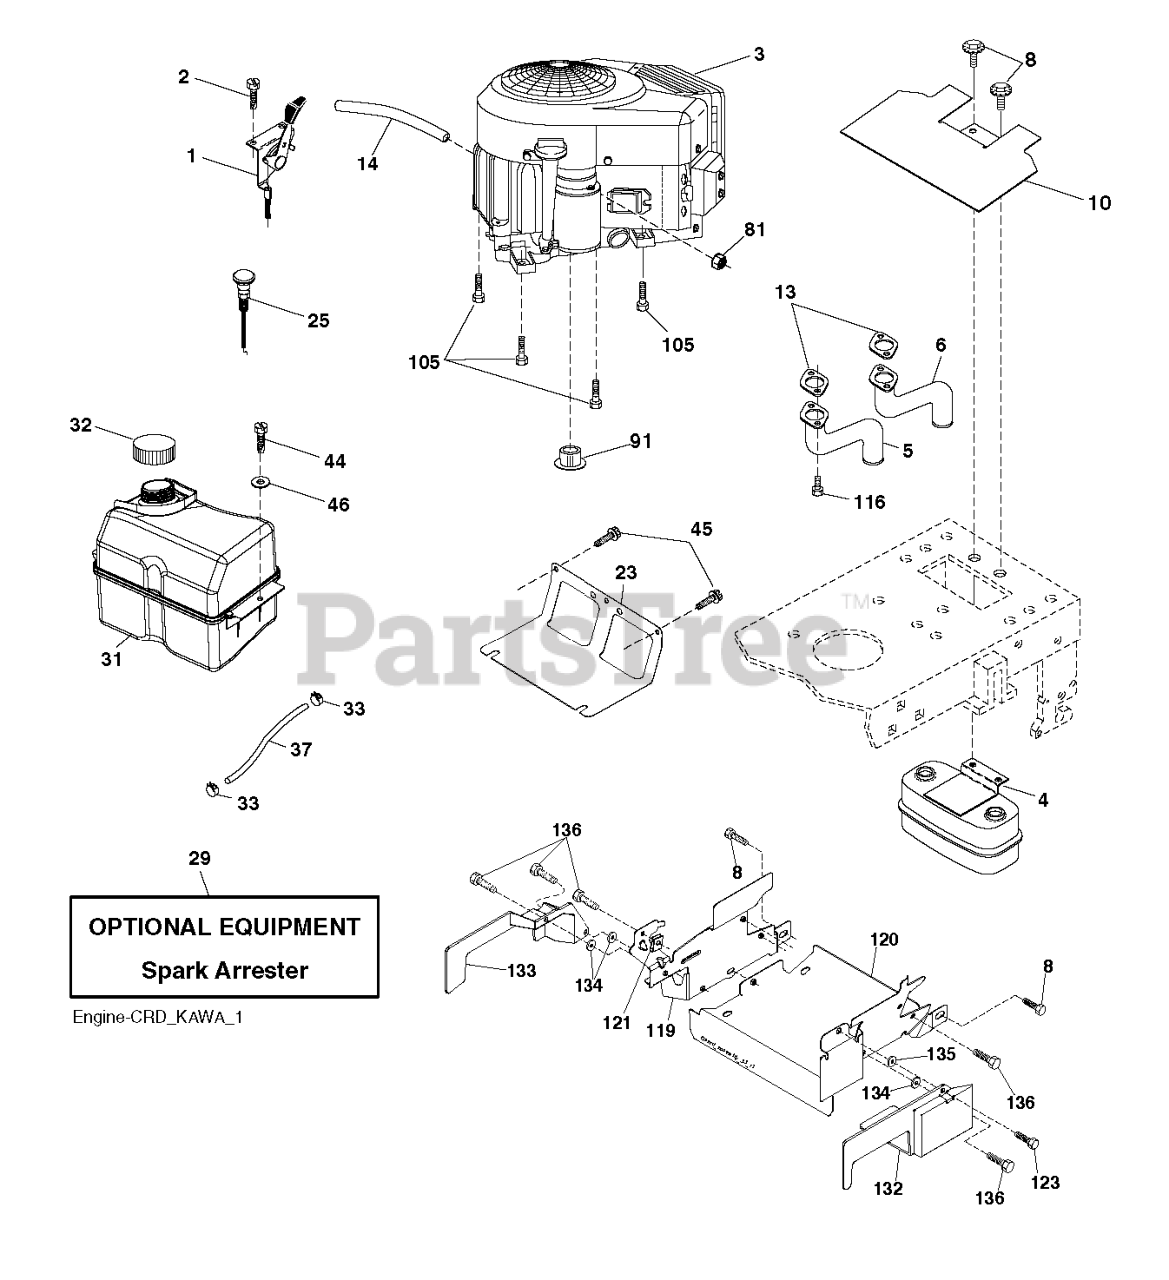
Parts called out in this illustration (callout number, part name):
1	THROTTLE CONTROL
2	SCREW
4	MUFFLER.TWIN.CYL.LOW.TONE
5	TUBE.EXHAUST.LH.FR961/FR730
6	TUBE.EXHAUST.RH.FR961/FR730
8	BOLT.5/16-18UNCX3/4 W/SEMS.BLK
10	SHIELD.HEAT.MUFFLER
14	TUBE, DRAIN OIL ASM.
23	SHIELD.BROWNING.DBR.GUARD
25	CONTROL, CHOKE, 37", PUSH
29	KIT.SPARK ARRESTOR 794945 B&S
31	TANK.ASM.FRNT.DAPCO.E10
32	CAP ASM.FUEL.2.25"FR.
33	HOSE CLAMP
37	LINE.FUEL.20
44	SCREW HEXWSHR 1/4-20X3/4
45	SCREW, 3/8-16X3/4
46	WASHER
81	NUT
91	BUSHING.1.375OD
105	SCREW 3/8-16X1
116	NUT.HEX.FLANGE.TOPLOCK
119	LENKRAD
120	GUARD 532199767
123	SCREW, 5/16-18 X 1/2
132	SHIELD RIGHT
133	SHIELD LEFT
134	PALNUT 1/4
135	WASHER 5/16"
136	SCREW.1/4-20X5/8
